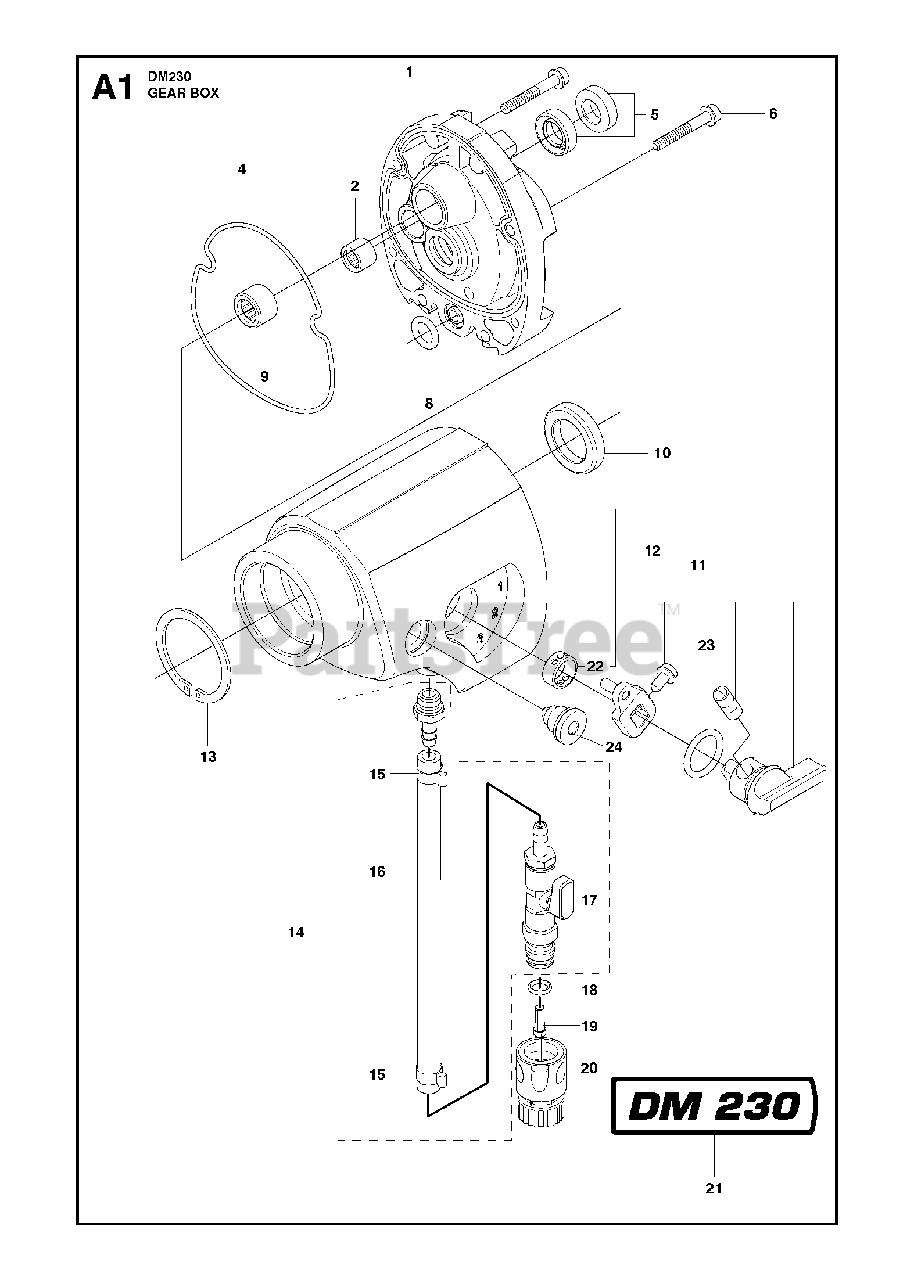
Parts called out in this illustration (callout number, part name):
4	SEALINGValid from machine serial number 20152200001
9	NEEDLE BEARING
20	COUPLERUSA/CANADA
